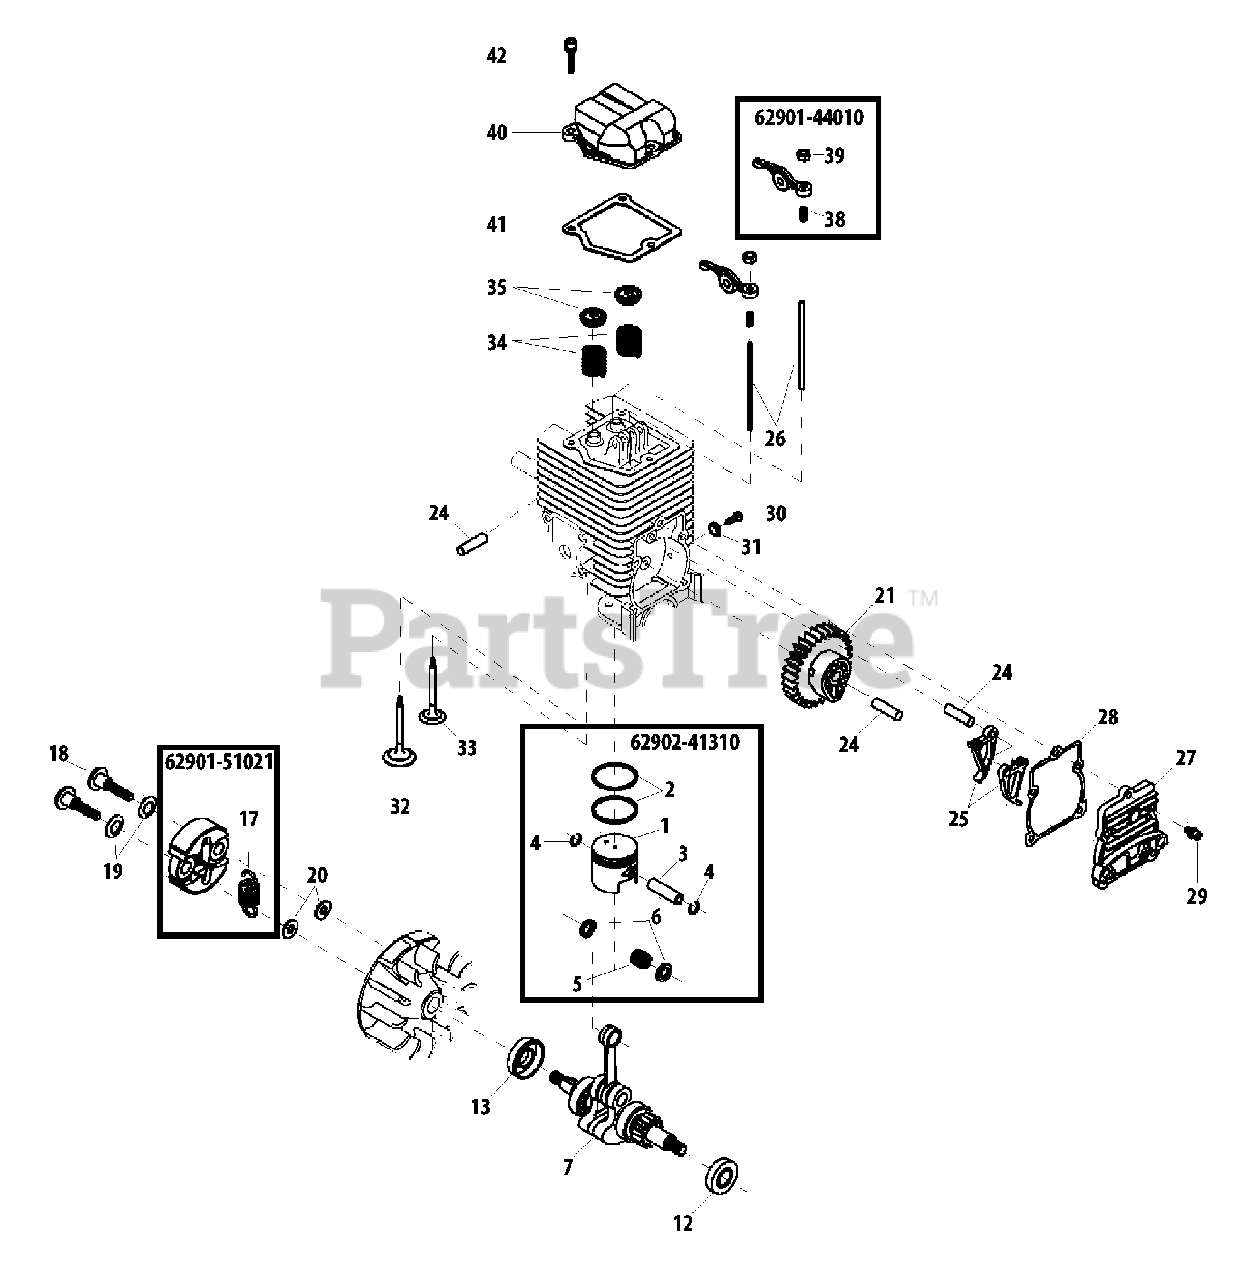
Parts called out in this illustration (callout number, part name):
1	PISTON
2	RING, PISTON
3	PIN, PISTON
4	RING, SNAP
5	BEARING, NEEDLE 9
6	WASHER, THRUST 9
7	CRANKSHAFT ASSY
12	SEAL, OIL 12
13	SEAL, OIL 12
17	SPRING, CLUTCH
18	BOLT, CLUTCH
19	WASHER, SPRING
20	WASHER 6 MM
21	GEAR, CAM
24	PIN, LOCATING Ø5×29.8 MM
25	FOLLOWER, CAM
26	PUSHROD
27	COVER, CAM GEAR
28	GASKET, CAM GEAR
29	BOLT M4×14
30	SCREW M5
31	WASHER Ø10ר5.5×2
32	VALVE, INTAKE
33	VALVE, EXHAUST
34	SPRING, VALVE
35	VALVE RETAINER ASSY
38	SCREW, ADJUSTER
39	LOCKNUT, ADJUSTER
40	COVER, ROCKER ARM
41	GASKET, ROCKER ARM
42	BOLT M4×12
62901-44010	ROCKER ARM ASSY
62901-51021	SHOE ASSY, CLUTCH
62902-41310	PISTON KIT
